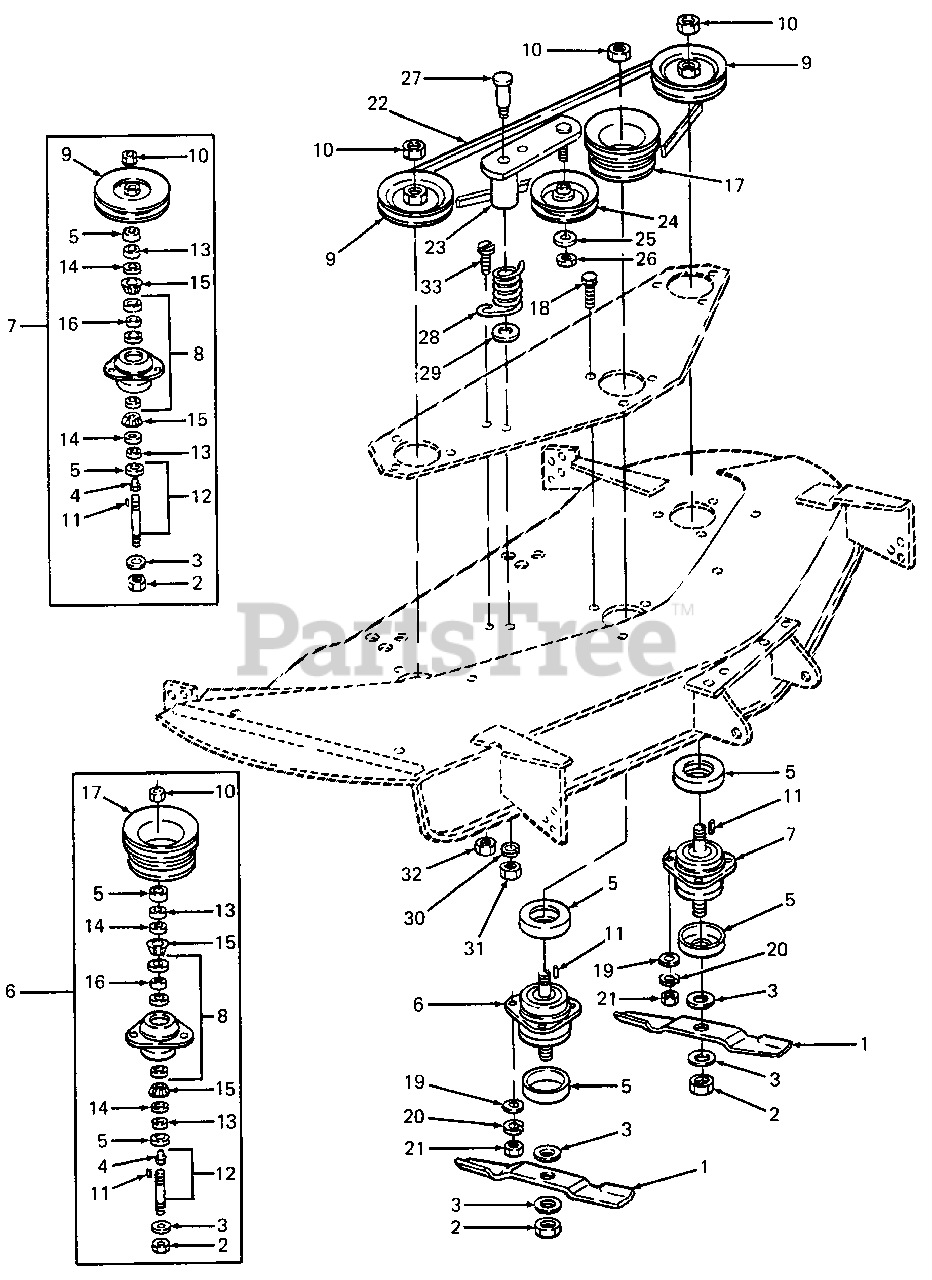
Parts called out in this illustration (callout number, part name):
1	Blade, Mower, 17.2 Lg
2	Nut, Hex, 3/4-16 GR8
3	Washer, Flat, .781 X 2.0 X .105 - Hdn
4	Fitting, Lube, 3/16
5	Cup, Spindle (HDN)
6	Spindle Service Kit - Center
7	Spindle Service Kit - Outside
8	Housing, Spindle w/Cups
9	4L V-Pulley, 4.62 OD X .75 ID
10	Nut, Hex Jam, 3/4-16
11	Key, #91 Woodruff, 1/4 X 3/4 - Hdn
12	Shaft, Blade w/Fitting
13	Spacer, .755 X 1.25 X .44 Lg
14	Seal, Oil, 1.25 X 1.874 X .25
15	Cone, Bearing
16	Spacer, Bearing
18	Screw, Hex Cap, 3/8-16 X 1.0 Lg GR5
19	Washer, Flat, .378 X 1.0 X .127 Thk
20	Washer, Lock, 3/8
21	Nut, Hex, 3/8-16 GR5
22	Belt, Spindle Drive
23	Arm Assy, Idler
24	Pulley, Flat Idler
25	Washer, Flat, .406 X .75 X .063 Thk
26	Nut, Hex Center Lock, 3/8-16 GR5
27	Bolt, Shoulder
28	Spring, Torsion
29	Washer, Flat, .469 X .875 X .105 Thk
30	Washer, Lock, 7/16
31	Nut, Hex, 7/16-14 GR5
32	Nut, Hex Insert Top Lock Jam, 3/8-16
33	Screw, Truss Hd, 3/8-16 X .75 Lg
